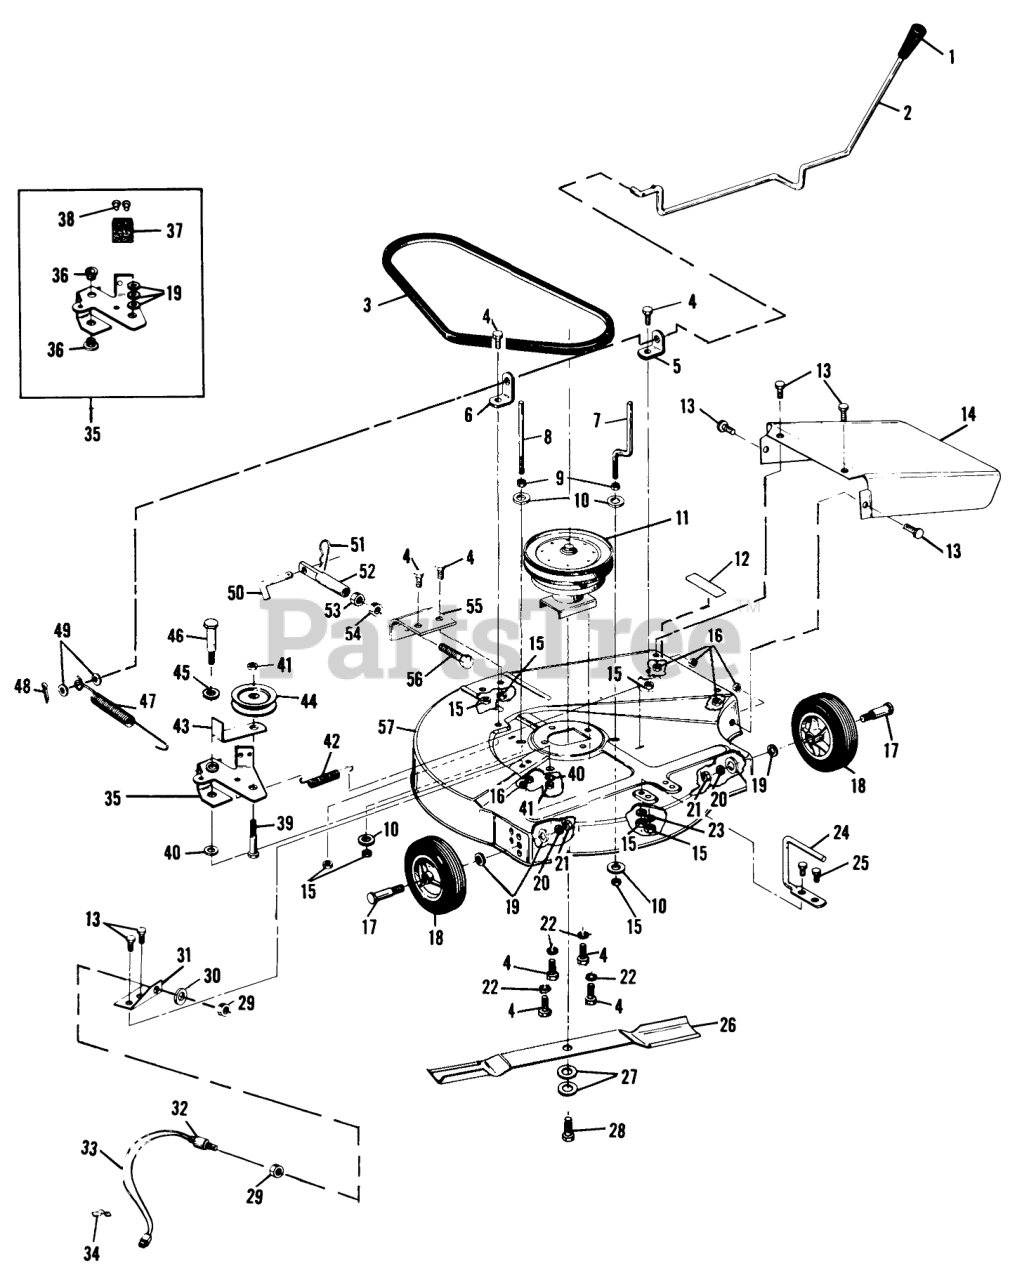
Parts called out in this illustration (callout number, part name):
2	Rod, Clutch
3	V-Belt, 4L-63
4	Bolt Hex 5/16-18
5	Bracket, Rod
6	Bracket Assy, Clutch Lever
7	Belt Guide
8	Guide, Belt
9	Nut 5/16-18 Keps
10	Washer
11	Quill Assembly
12	Decal, Caution, Blade Engage
13	Bolt, 1/4-x 1/2
14	Chute Deflector
15	Nut-Nylok
16	Locknut, Hex, 1/4-20 Thd
17	Shoulder Bolt
18	Wheel
19	Washer
20	Lockwasher
21	Nut
22	Lockwasher
23	Washer
24	Guide, Rear
25	Bolt, 5/16-18 X 7/8
26	Blade, 26 In.
27	Spring Washer
28	Bolt-Nylok 3/8-24 x 1
29	Nut (Switch Part)
30	Lockwasher (Switch Part)
31	Bracket, Safety Switch
32	Safety Switch
33	Wire Assy, Deck Switch
34	Press Clip
35	Arm Assembly, Idler
36	Bushing
37	Pad Brake
38	Rivet
39	Bolt, 3/8 16 x 2
40	Flatwasher, 3/8 In.
41	Nut
42	Spring, Brake
43	Arm, Idler
44	Pulley, Idler
45	Washer
46	Shoulder Bolt
47	Spring, Mower Clutch
48	Cotter Key
49	Washer
50	Pull Pin
51	Hairpin Cotter
52	Hitch, Deck Front
53	Locknut, Hex, 5/8-11 Thd
54	Locknut, Jam, Hex, 5/8-11 Thd
55	Plate, Front
56	Bolt, Hex Hd, 5/8-11 x 3 1/2 In.
57	Mower Deck
